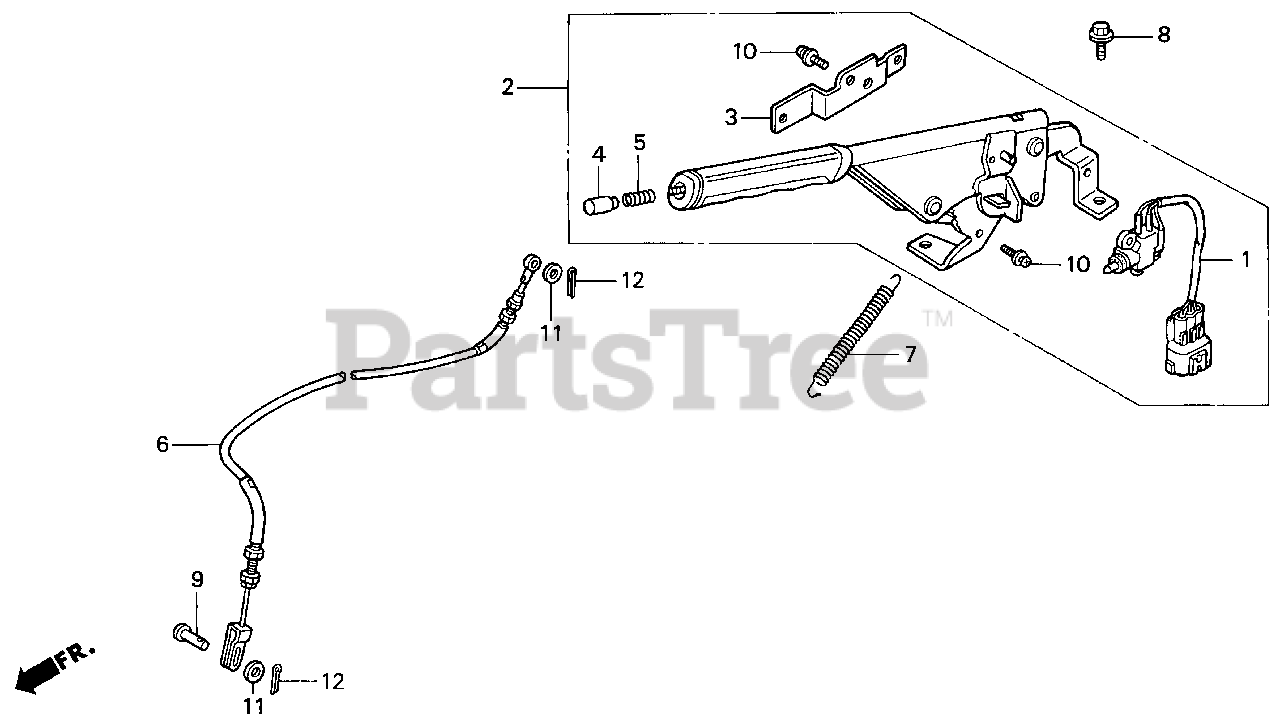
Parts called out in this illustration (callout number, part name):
1	SWITCH ASSY., PARKING BRAKE
2	LEVER ASSY., PARKING BRAKE *YR161* (ORANGE)
3	BRACKET, SWITCH
4	KNOB, PUSH ROD *YR161* (ORANGE)
5	SPRING, PUSH ROD
6	CABLE, PARKING BRAKE
7	SPRING, PARKING BRAKE LEVER
8	BOLT, FLANGE (8X16)
9	PIN, CLUTCH JOINT
10	SCREW-WASHER (4X12)
11	WASHER, PLAIN (6MM)
12	PIN, COTTER (1.6X12)
